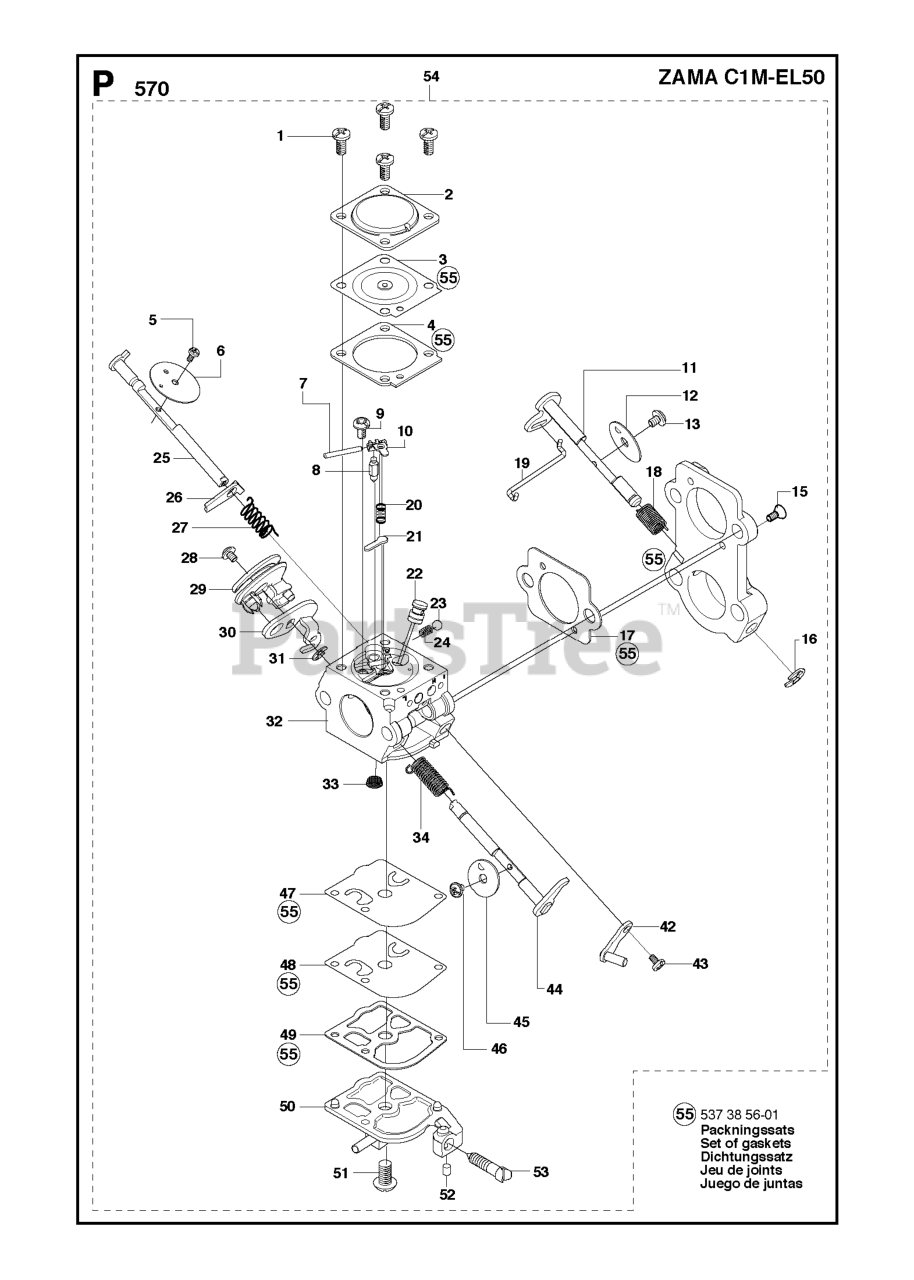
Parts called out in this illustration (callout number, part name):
6	CHOKE FLAP
7	PIN RETAINING SCREW
8	INLET NEEDLE
12	THROTTLE FLAP
25	CHOKE SHAFT
32	CARBURETTOR
39	LIMITER CAP KIT
47	PUMP DIAPHRAGM
54	CARBURETTOR
55	GASKET SET
